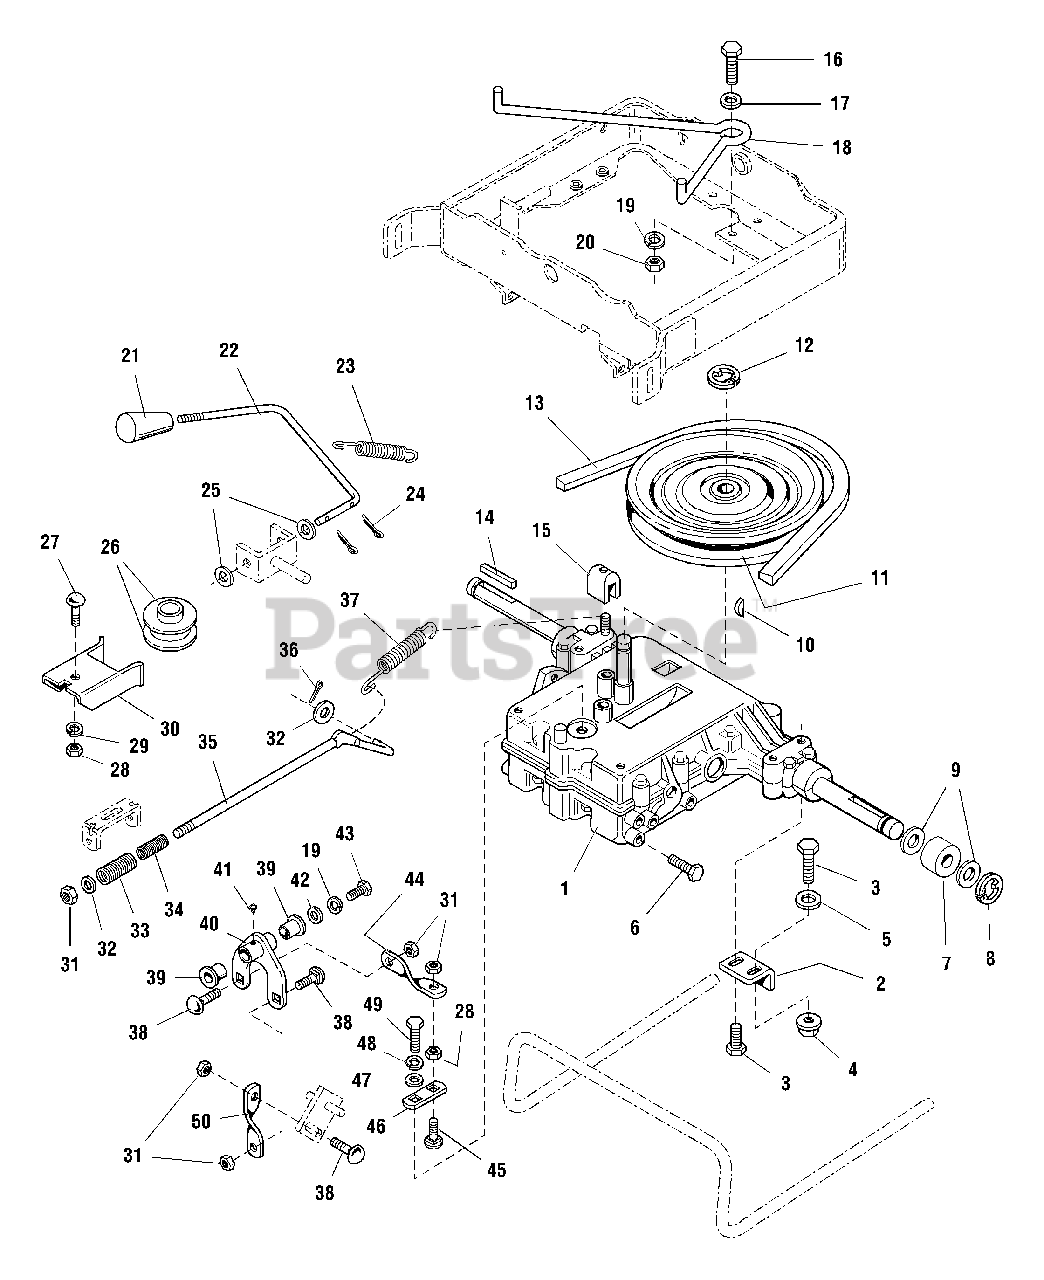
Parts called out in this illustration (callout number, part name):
1	TRANSMISSION ASSEMBLY
2	ANCHOR, Torsion Bar
3	CAPSCREW, Taptite Hex Washer Hd, 5/16-18 x 2-1/2
4	NUT, Hex, Flange Whiz Lock, 5/16-18
5	WASHER, 5/16
6	CAPSCREW, Taptite Hex Washer Hd, 5/16-18 x 5/8
7	SPACER
8	E-RING
9	WASHER, 3/4
10	KEY, Woodruff #9
11	PULLEY ASSEMBLY
12	RING, Retaining
14	KEY
15	SPEED NUT, "U" Type, #14A
16	CAPSCREW, Hex Hd, 3/8-16 x 1-1/4
17	WASHER, Plain, 3/8
18	GUIDE, Belt
19	LOCKWASHER, 3/8
20	NUT, Hex, Full, 3/8-16
21	KNOB, Plastic, Gear Shift
23	SPRING, Gear Shift
24	PIN, Cotter, 3/32 x 1
25	WASHER, 1/2
26	PULLEY HALF, Engine PTO
27	CARRIAGE BOLT, 5/16-18 x 3/4
28	NUT, Hex, Full, 5/16-18
29	LOCKWASHER, 5/16
30	GUARD, Belt
31	NUT, Hex Nylon Lock, 5/16-18
32	WASHER, Plain, 5/16
33	SPRING, Compression
34	SPRING, Compression
36	PIN, Cotter, 3/32 x 3/4
37	SPRING, Return
38	CARRIAGE BOLT, 5/16-18 x 1-1/4
39	BUSHING, Plastic, 5/8
40	BELLCRANK ASSY
41	FITTING, Grease
42	WASHER, Plain, 3/8
43	CAPSCREW, Hex Hd., 3/8-16 x 3/4
44	LINK, Shift, Lower
45	CARRIAGE BOLT, 5/16-18 x 1-1/2
46	LEVER, Shift
47	WASHER, Plain, 1/4
48	LOCKWASHER, 1/4
49	CAPSCREW, Hex Hd, 1/4-28 x 5/8
50	LINK, Shift, Upper
